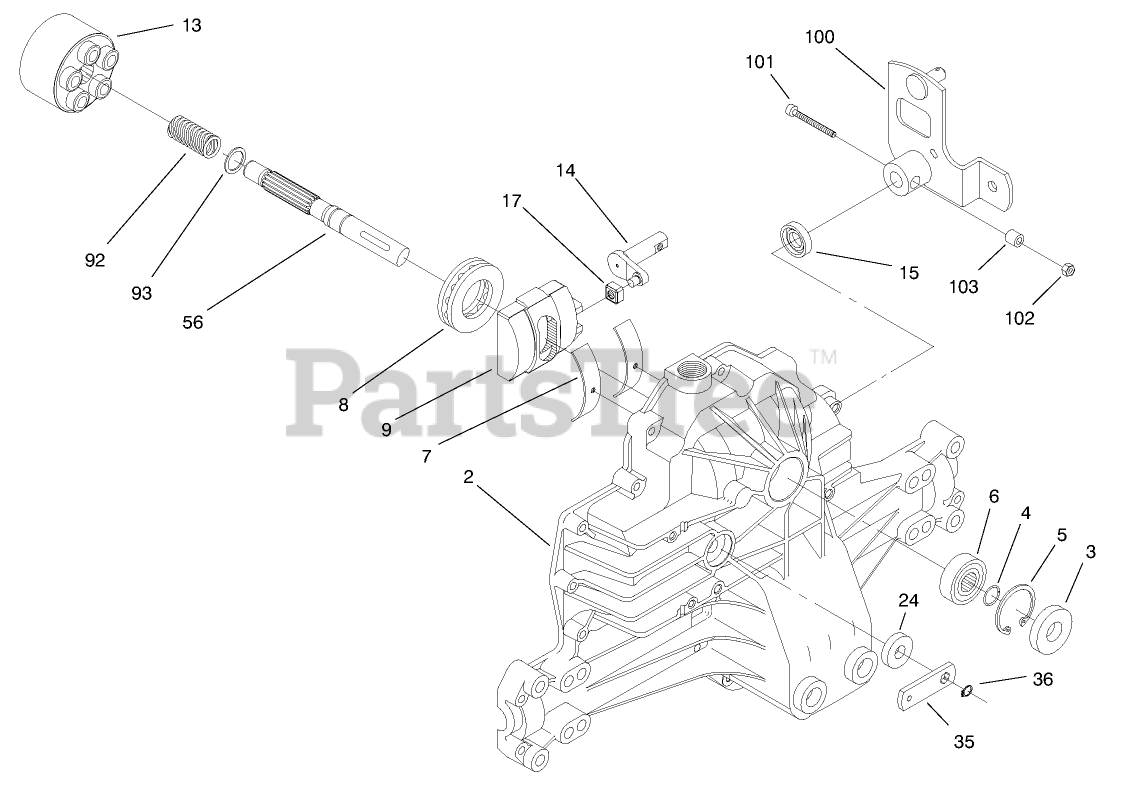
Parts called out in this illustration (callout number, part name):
3	Seal-Lip
4	RING-WIRE, RETAINING
5	RING-RETAINING
6	BEARING-SHAFT, BALL
7	BEARING-CRADLE
8	BEARING-THRUST
9	SWASHPLATE-VARIABLE
14	ARM-TRUNION
15	SEAL-LIP
17	GUIDE-SLOT
24	SEAL-LIP
35	ARM - BYPASS
36	RING-RETAINING
56	SHAFT - INPUT
92	SPRING-BLOCK
93	WASHER-THRUST
100	WA - SPEED CONTROL LEVER
101	SCREW-HSH
102	NUT-LOCK, NI
103	LOCK SPACER
